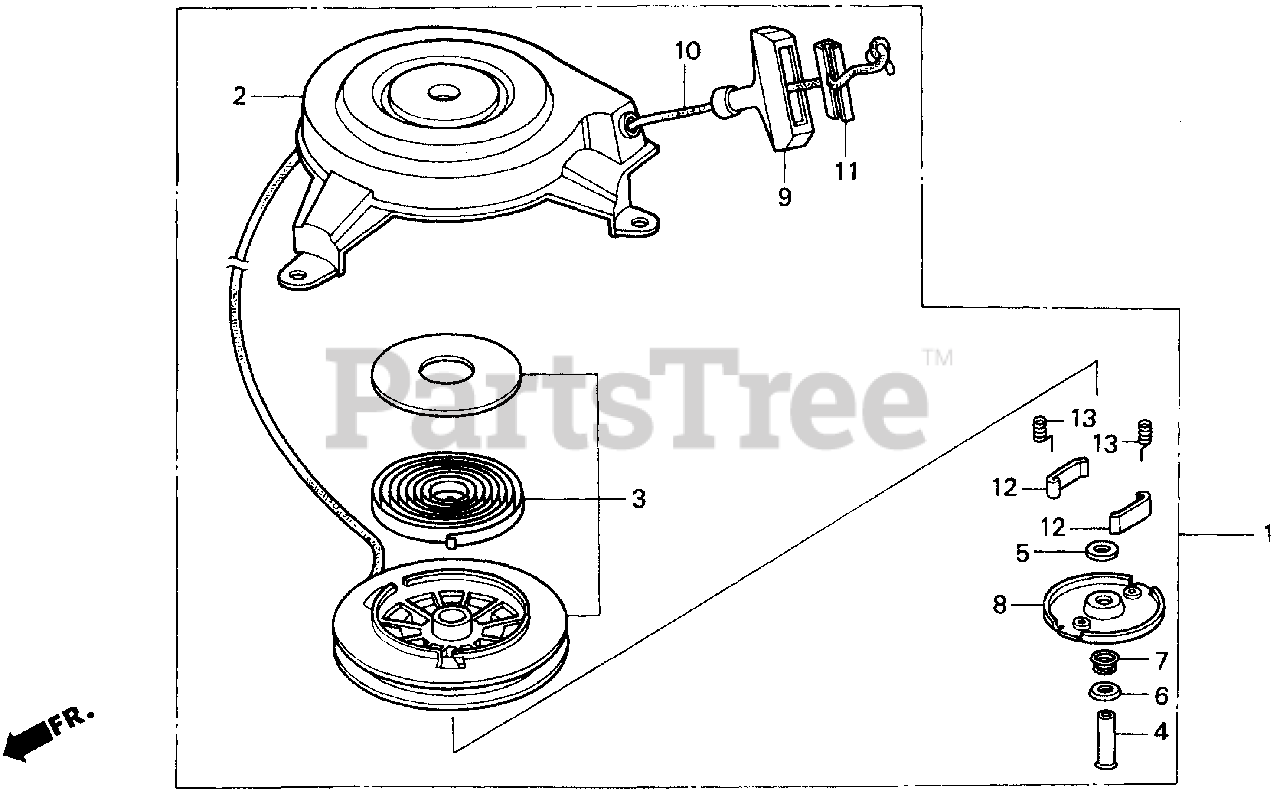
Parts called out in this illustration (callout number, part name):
1	STARTER ASSY., RECOIL
2	HOUSING ASSY. (NA USE ALT:28400-ZG9-803)
3	PULLEY & SPRING ASSY.
4	PIN, CENTER
5	PLATE A, FRICTION
6	PLATE B, FRICTION
7	SPRING, FRICTION
10	ROPE, RECOIL STARTER
11	HANDLE, REINFORCEMENT
13	SPRING, DOG
